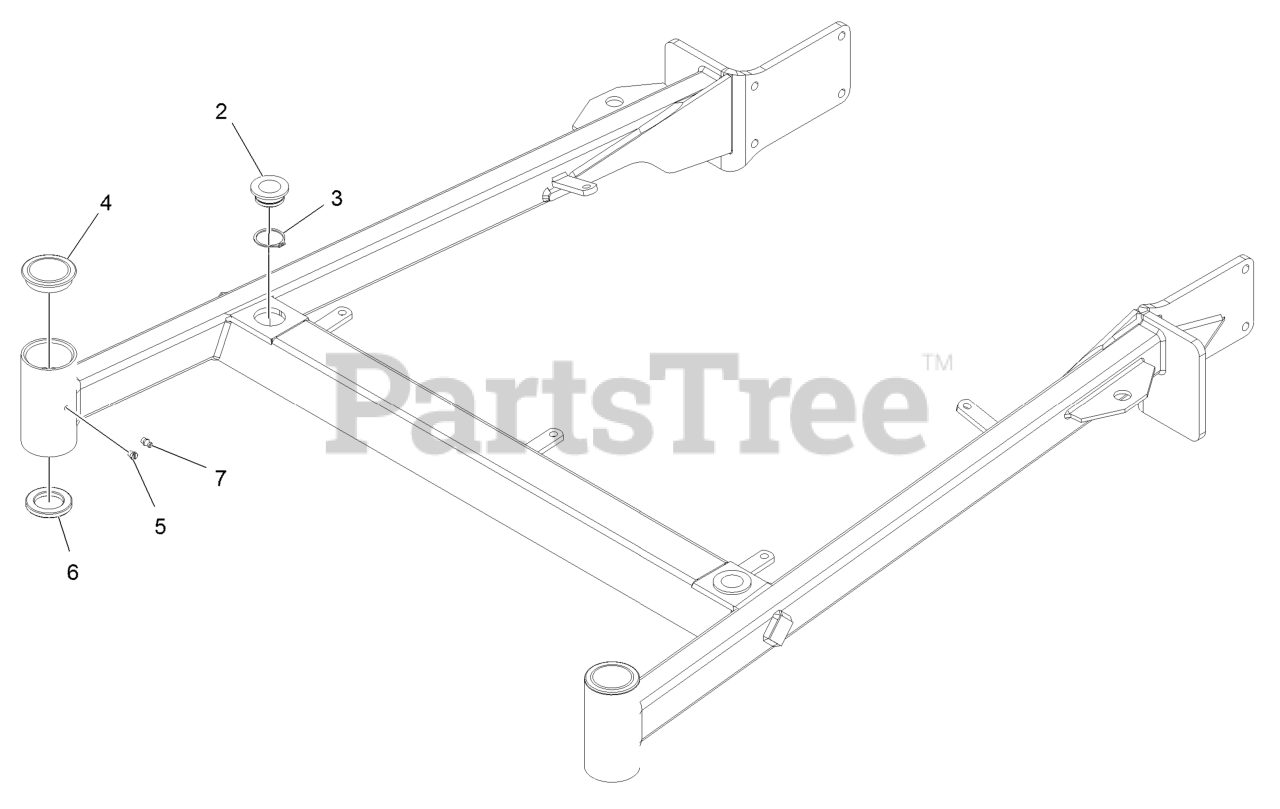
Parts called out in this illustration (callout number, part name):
2	BUSHING-DECK
3	RING-RETAINING
4	CAP-GREASE
6	SEAL-GREASE
7	FITTING-GREASE
